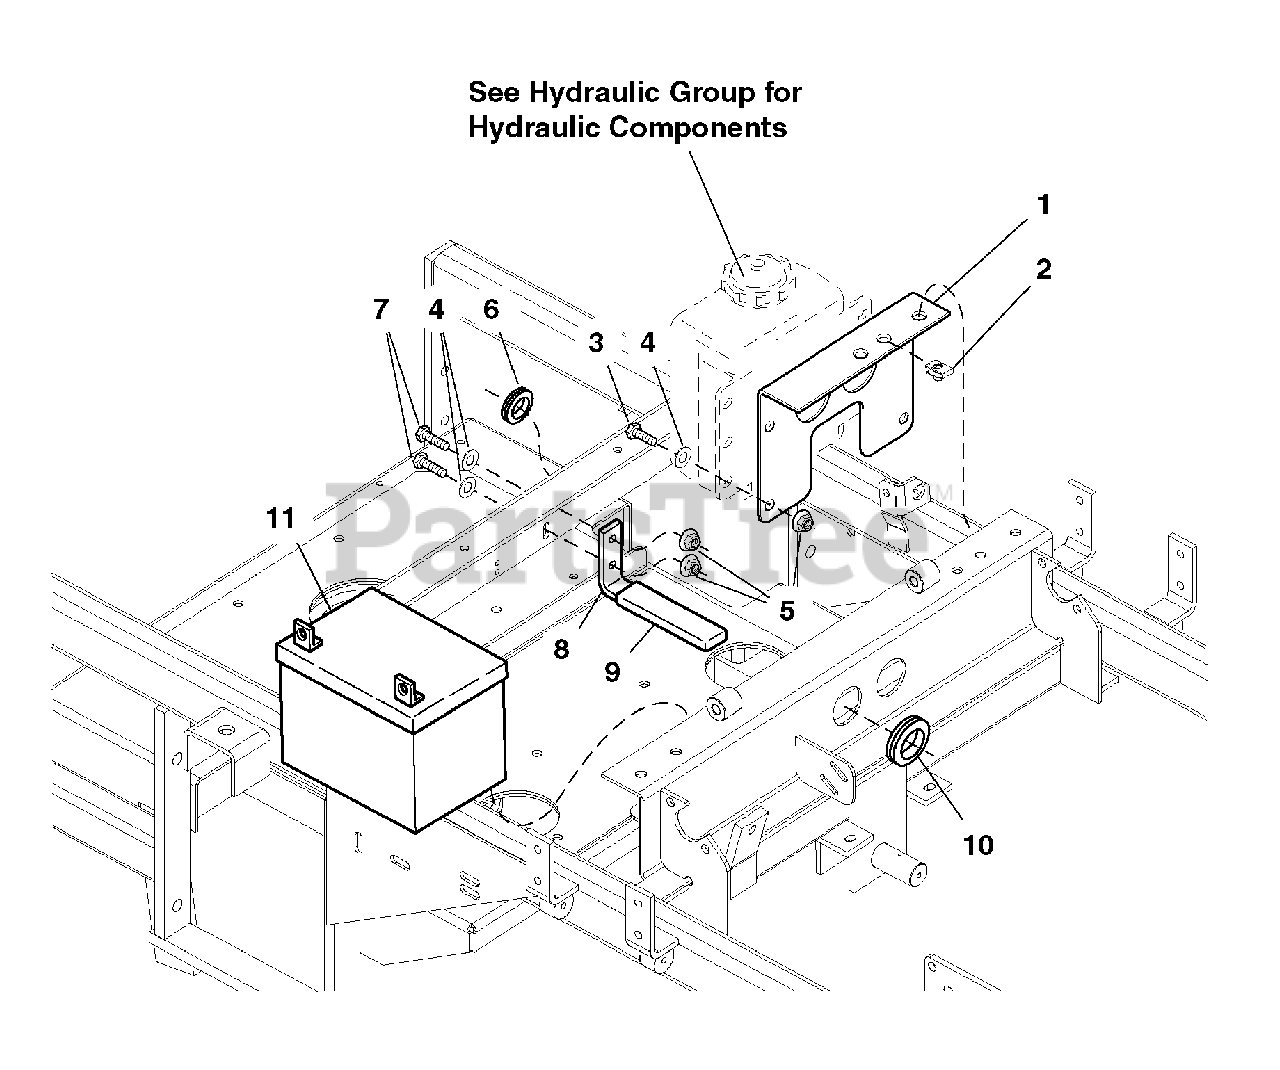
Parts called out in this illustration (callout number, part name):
1	MOUNT, Reservoir
2	BODY CLIP, 3/8-16
3	CAPSCREW, Hex Hd, 5/16-18 x 3/4
4	WASHER, 5/16
5	NUT, Hex, Serrated Flange, 5/16-18
6	GROMMET, 7/8
7	CAPSCREW, Hex Hd, 5/16-18 x 1
8	RETAINER, Battery
10	GROMMET, 1-1/4
11	BATTERY, Dry Cell (12V, 400CA Lawn & Garden)
